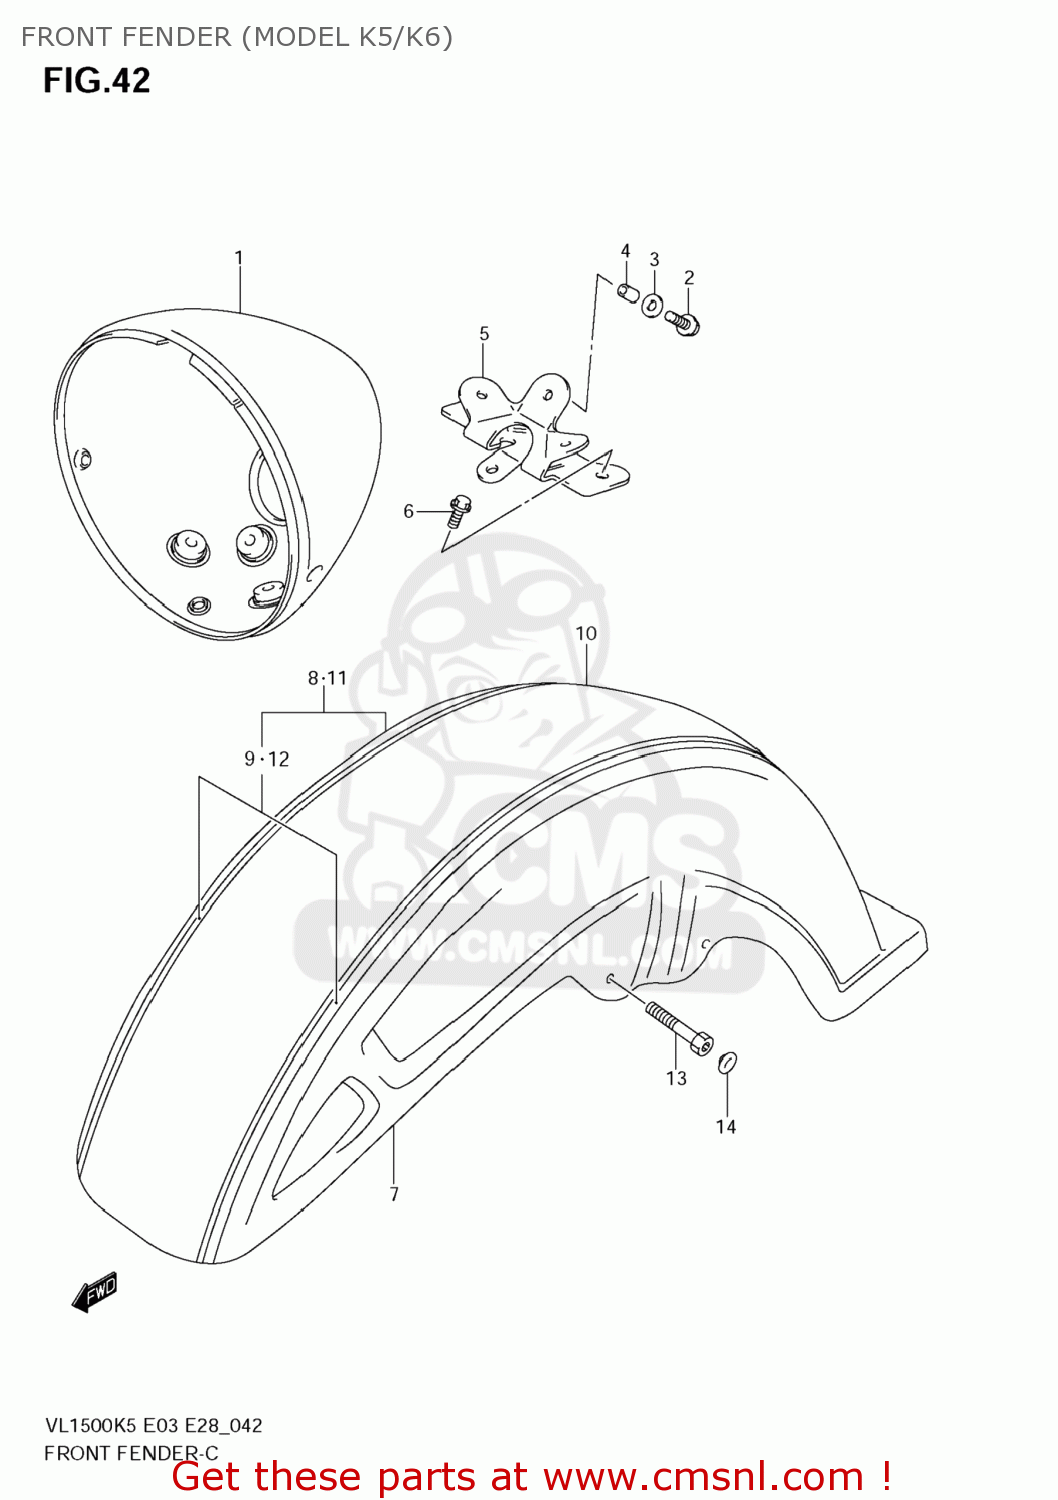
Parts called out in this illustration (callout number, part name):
1	HOUSING ASSY,HEADLAMP
2	BOLT
3	WASHER(6.5X20X1.2)
4	SPACER(6.5X9X10)
5	BRACKET,HEADLAMP HOUSING
6	BOLT
7	FENDER,FR
8	FENDER ASSY,FR
9	TAPE SET,FR FENDER
10	FENDER,FR
11	FENDER ASSY,FR
12	TAPE SET,FR FENDER
13	BOLT
14	CAP(OD:11)
